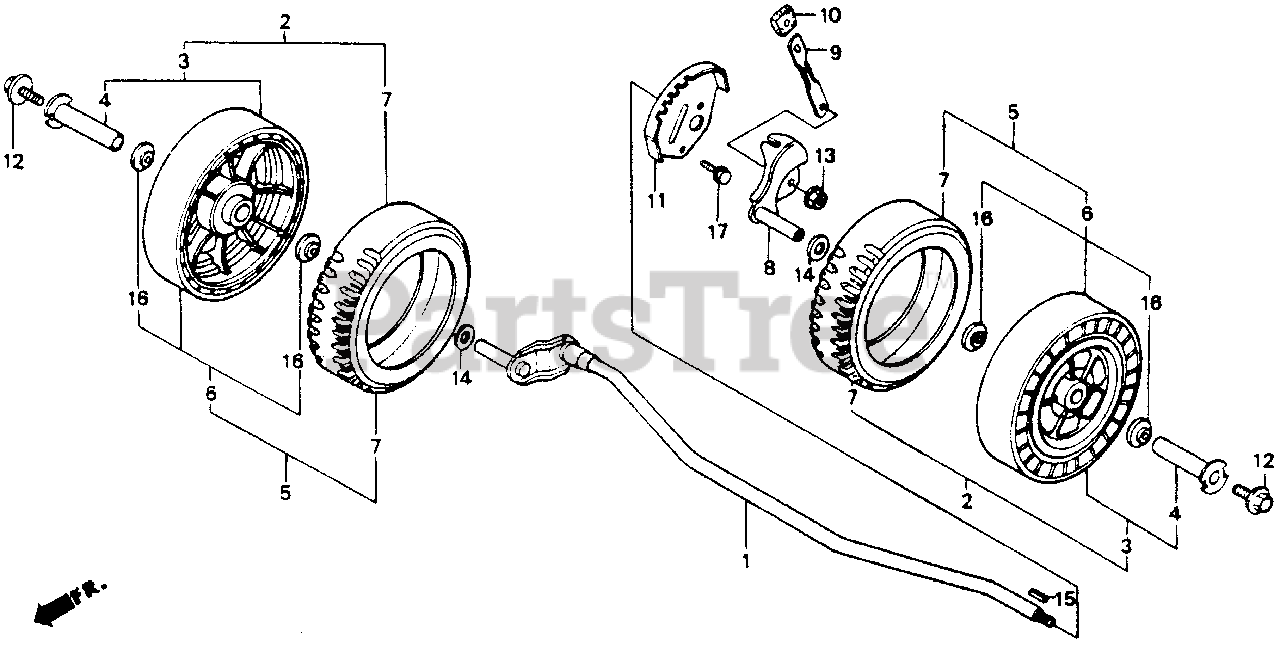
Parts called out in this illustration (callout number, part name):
1	SHAFT, FR. AXLE
5	WHEEL (8") *NH31* (MCKINLEY WHITE)
6	HUB, WHEEL (NA USE ALT:42710-VA3-J00)
7	TIRE (8 INCH)
8	ARM, L. FR. ADJUSTER
9	PLATE, FR. ADJUSTER
10	GRIP, ADJUSTER
11	PANEL, FR. ADJUSTER
12	BOLT, WHEEL
13	NUT, FLANGE (8MM)
14	WASHER, WHEEL
15	KEY (4X4X11)
16	BEARING, RADIAL BALL
17	BOLT, FLANGE (6X12)
